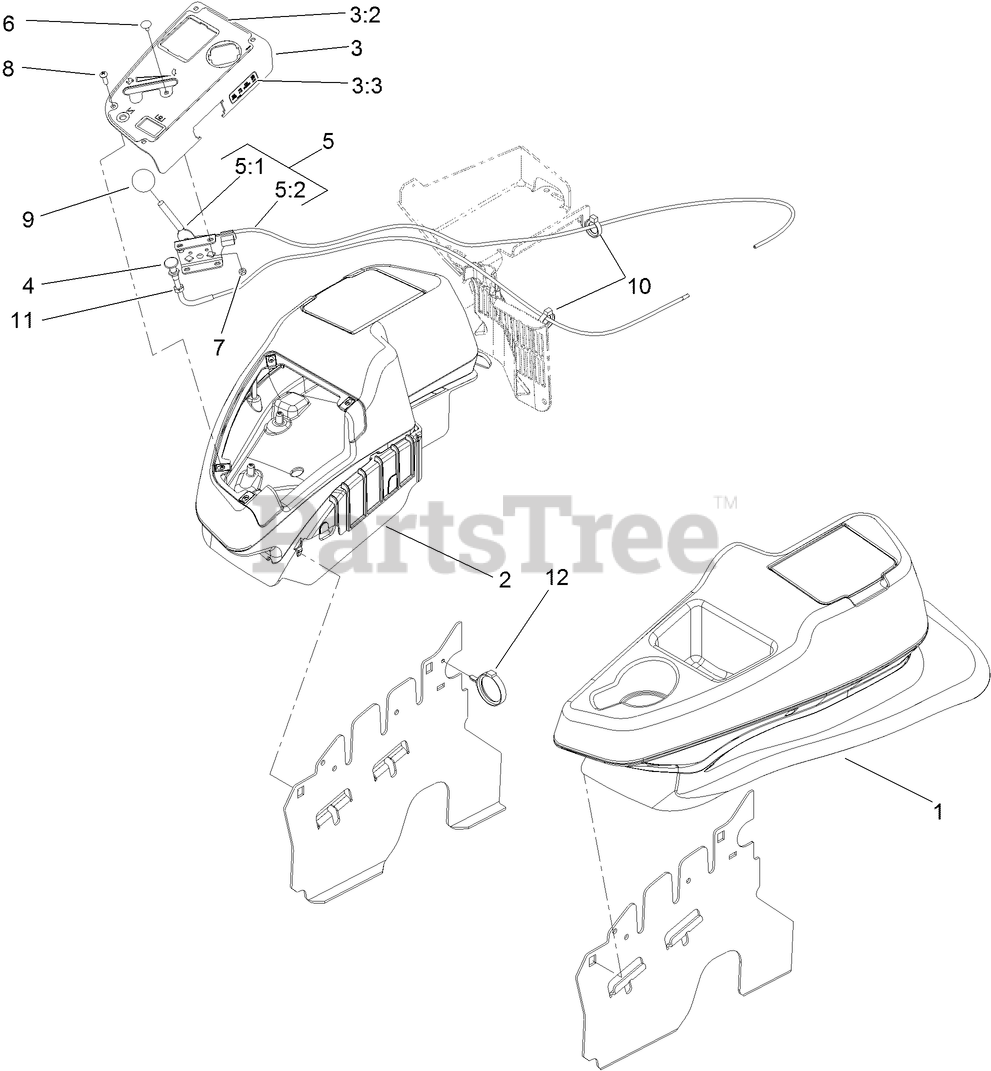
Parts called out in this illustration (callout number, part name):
1	LH CONSOLE ASM
2	RH CONSOLE ASM
3	CONTROL PANEL ASM
3:2	DECAL-PANEL, CONTROL
3:3	DECAL-FUSES
4	CHOKE CONTROL ASM
5	THROTTLE CONTROL ASM
5:1	LEVER-THROTTLE
5:2	CABLE-THROTTLE
6	BOLT-CARR
7	NUT-LOCK, NI
8	SCREW-HWH
9	KNOB-BALL
10	CLAMP-HOSE
11	NUT-HJ
12	CLAMP-HARNESS
